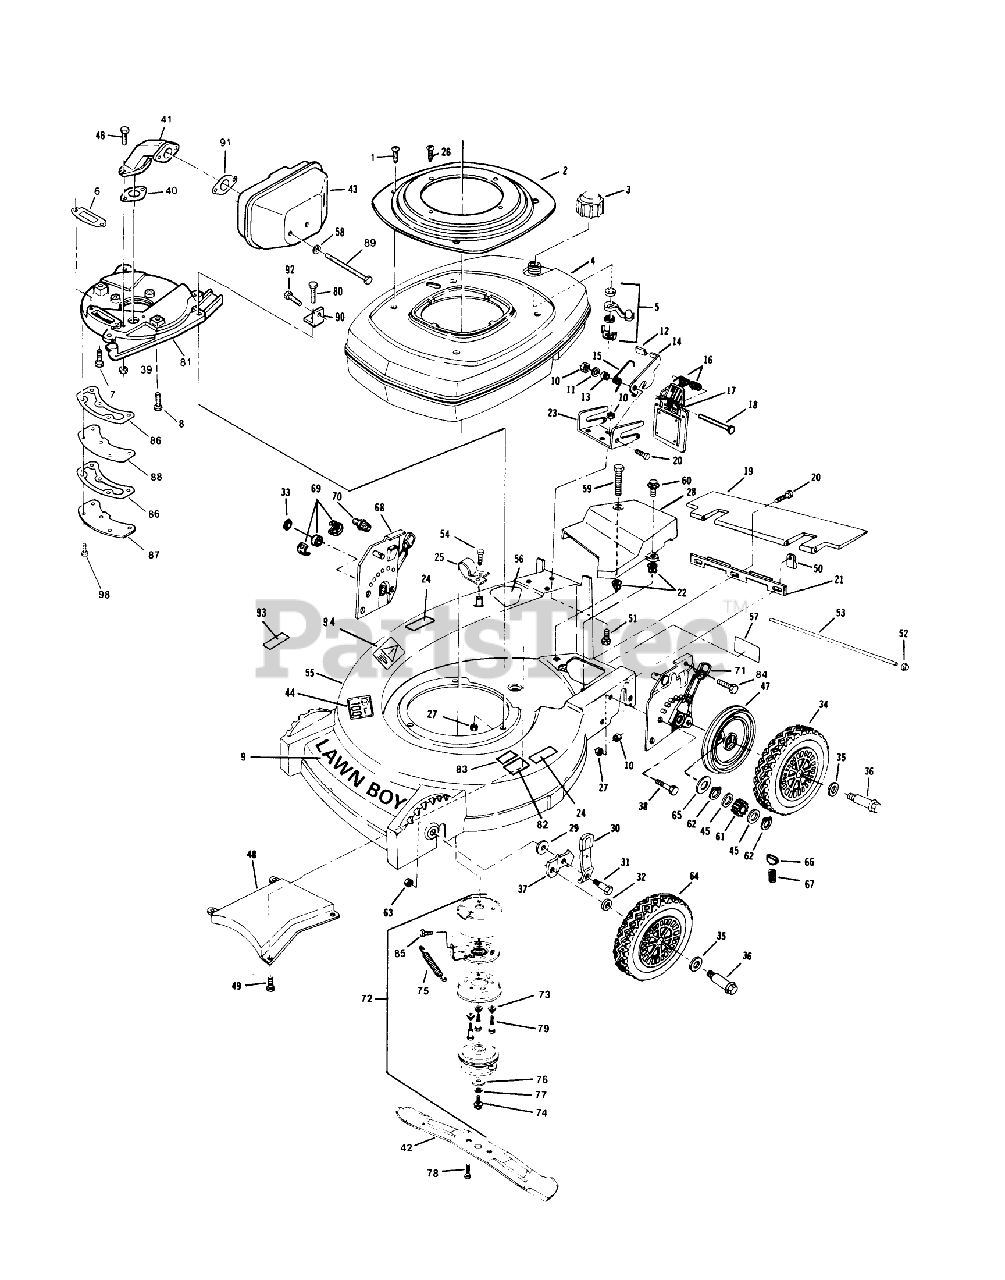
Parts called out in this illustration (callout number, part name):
3	FUEL CAP & INSERT
5	SHUT-OFF VALVE S
8	SCREW V
10	LOCKNUT E
12	KNOB (S&R)
15	SPRING
16	SPRING ASOC
18	ROD (RB&W)
19	T/SHIELD SM&P
26	SCREW SEMS SM
27	NUT-LOCK F
29	WASHER
30	SPRING ARM ASM
31	BOLT
32	WASHER WROUGHT
33	WASHER
35	SPACER
36	BOLT WHEEL
39	LOCKNUT E
45	SPACER/GR ALGHNY
48	BAFFLE CHUTE PL
54	SCREW LAWRENCE
60	SCREW
61	PINION BROCKWAY
62	RET RING
63	LOCKNUT
64	WHEEL&TIRE 8" TRI
65	THRUST WASHER
66	KEY
67	SPRING
69	REAR AXLE BEARING
70	**FITTING LINCOLN
75	SPRING
76	WASHER
78	SCREW SEMS
79	SCREW,SHOULDER SM
80	SCREW
82	PAD FOOT
86	GASKET S
87	COVER HIP
91	GASKET S
92	SCREW-SEMS
